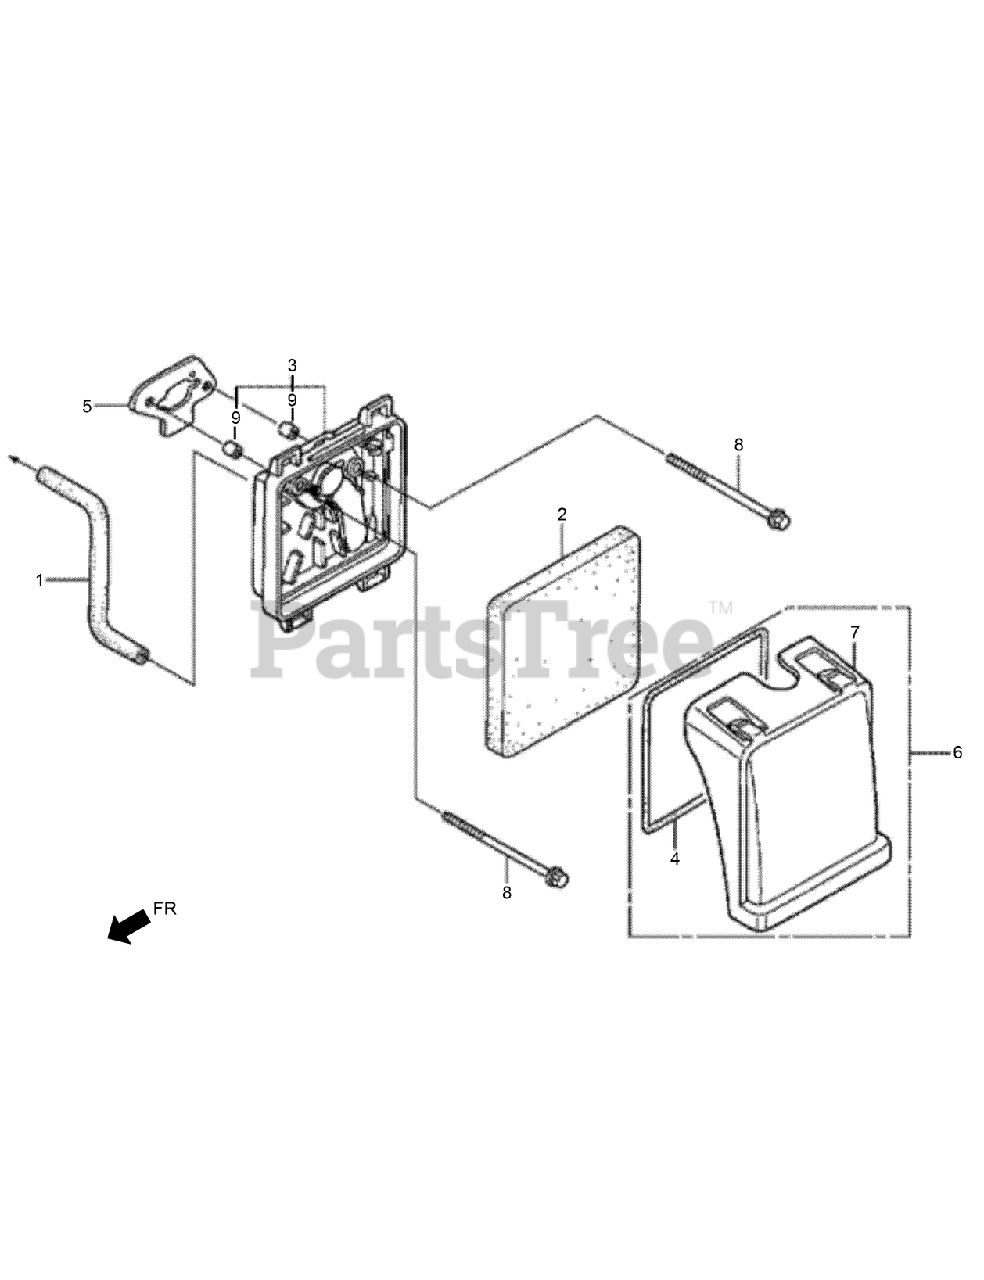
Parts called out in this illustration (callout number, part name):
1	TUBE-BREATHER
2	ELEMENT-AIR CLEANER
3	AIR CLEANER CASE ASM
4	SEAL-AIR CLEANER
5	PACKING-AIR CLEANER
6	AIR CLEANER COVER ASM
7	COVER-AIR CLEANER
8	BOLT-FLANGE-5X65
9	COLLAR-AIR CLEANER
